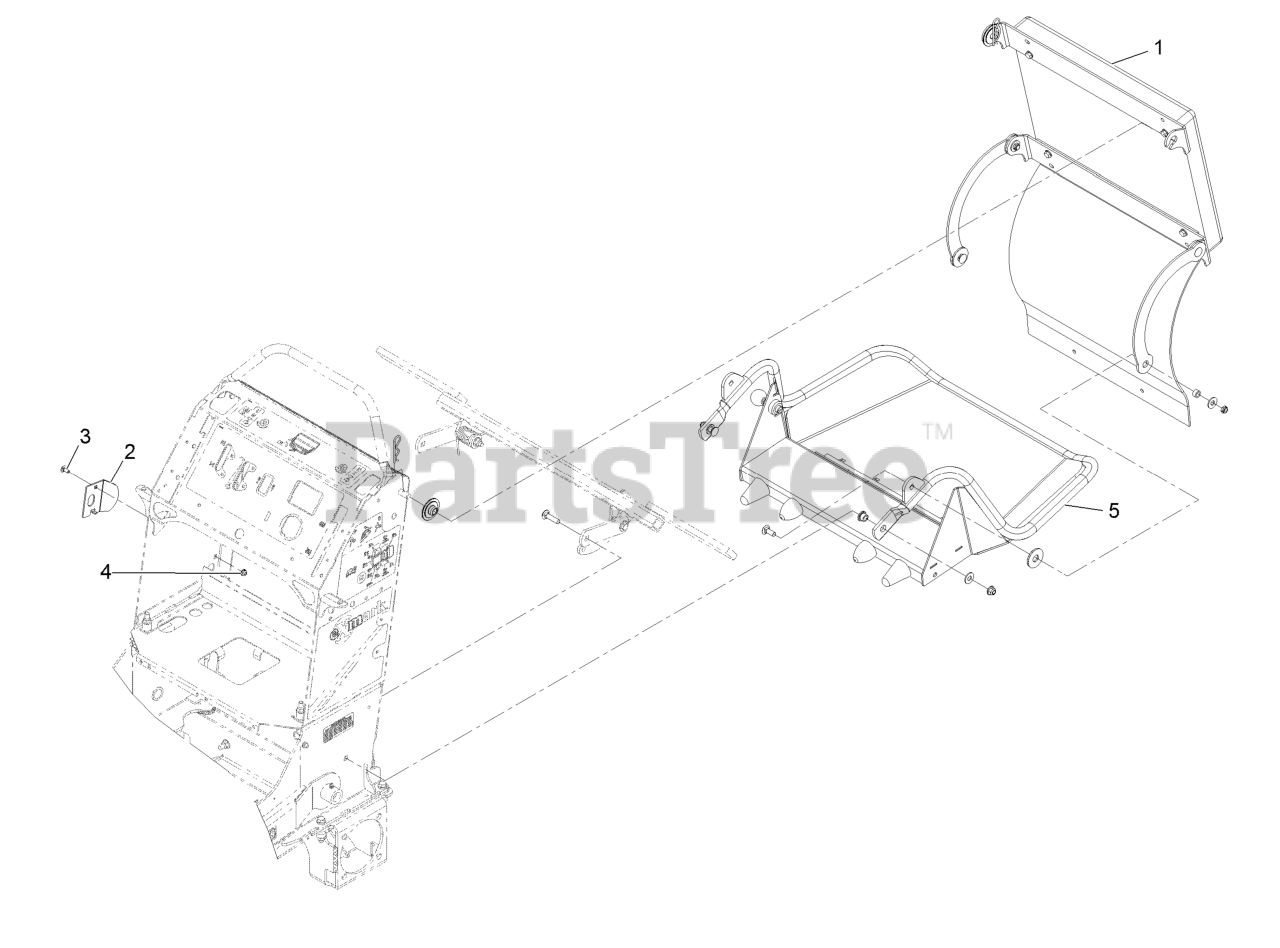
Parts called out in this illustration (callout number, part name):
1	ASM, Cushion
2	Plate-Striker
3	Bolt-Carriage 1/4-20 X 5/8
4	Nut-Nyloc 1/4-20 Flg
5	ASM,Platform
